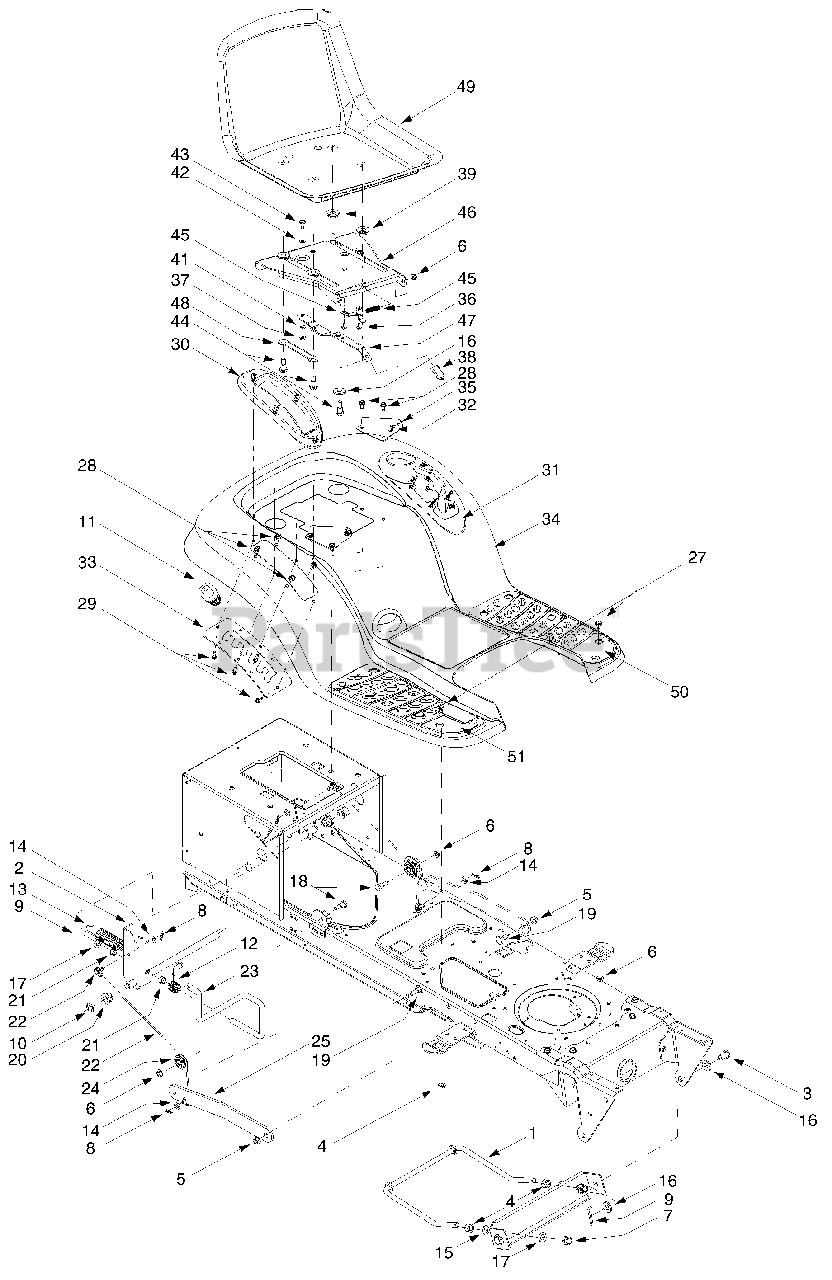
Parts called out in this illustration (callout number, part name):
1	Deck Stabilizer Rod
3	Clevis Pin, .5 x .78
4	Hex Nut, 1/2-13
5	Flange Lock Nut, 3/8-16
6	Flange Lock Nut, 5/16-18
7	Hex Nut, 1/2-13
8	Internal Cotter Pin
9	Cotter Pin
11	Handle Grip
12	Torsion Spring
13	Lift-assist Spring, 1.15 x 5.99
14	Flat Washer, 5/16
15	Lock Washer, 1/2
16	Flat Washer, .31 x 1.062 x .134
17	Flat Washer, .51 x 1.12 x .06
18	Hex Cap Screw, 5/16-18 x .62
19	Shoulder Screw, .5 x .27, 3/8-16
20	Hex Flange Bearing
21	Snap Flange Bearing
22	Lift Cable, 16.16
23	Lift Handle
24	Roller Pulley
27	Carriage Bolt, 5/16-18 x .62
28	Self Tapping Screw, 5/16-18 x .625
29	Self Tapping Screw, 1/4-15 x .75
30	Lift Lever Cover
31	Shift Lever Cover w/ Cup Holder
32	Shoulder Screw, .437 x 1.62
36	Screw, #10-16 x .375
37	Hex Flange Lock Nut, 1/4-20
38	Seat Adjuster Grip
41	Spring Washer, .265 x .562 x .025
42	Flat Washer, .344 x .62 x .03
43	Shoulder Screw, .340 x .285,1/4-20
44	Shoulder Screw, .50 x .50, 3/8-16
45	Seat Stop
48	Seat Adjustment Selector
49	Seat
50	LH Foot Pad
51	RH Foot Pad
